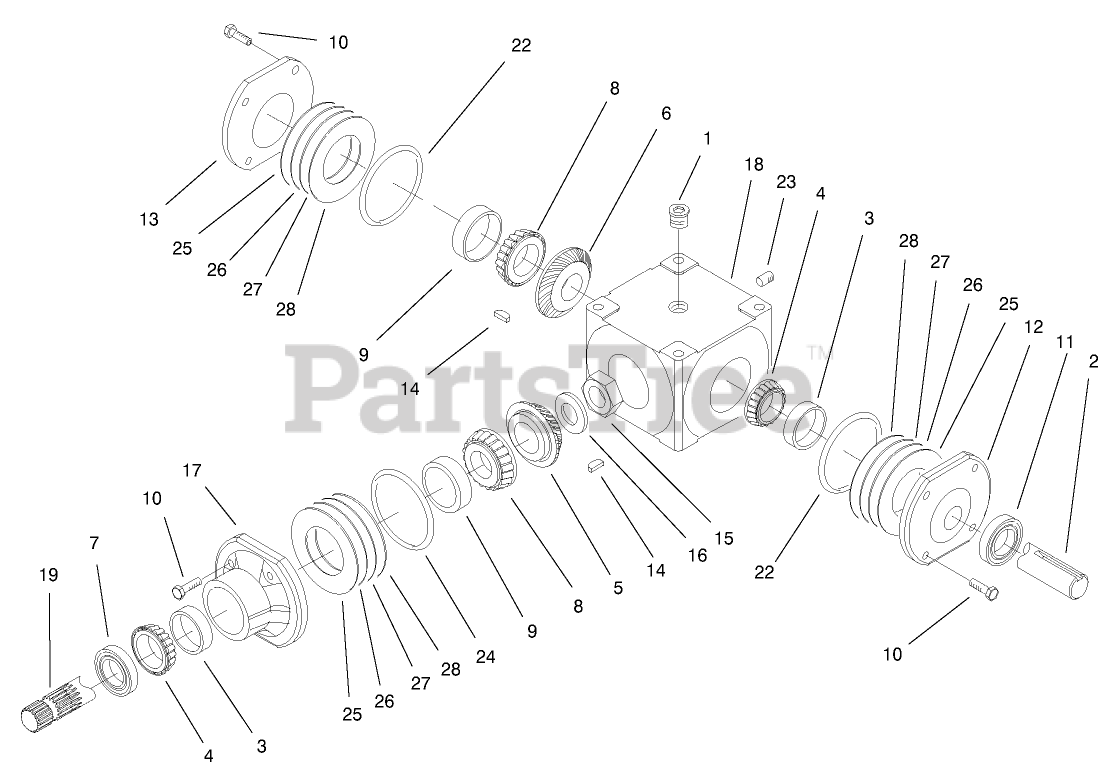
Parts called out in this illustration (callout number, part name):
2	SHAFT-CROSS
3	Bearing-Cup
4	Bearing-Cone
5	GEAR-SPIRAL, RH
6	GEAR-SPIRAL, LH
8	BEARING-CONE
9	BEARING-CUP
10	SCREW-HH
11	SEAL
12	CAP-END
13	CAP-END, CLOSED
14	OBS KEY
15	NUT-LOCK
16	WASHER
17	HOUSING-PINION
19	SHAFT-PINION
22	O-RING
24	O-RING
25	SHIM-GREEN (.003IN)
26	SHIM-BLUE (.005)
27	SHIM-BROWN (.010)
28	SHIM-YELLOW (.020IN)
